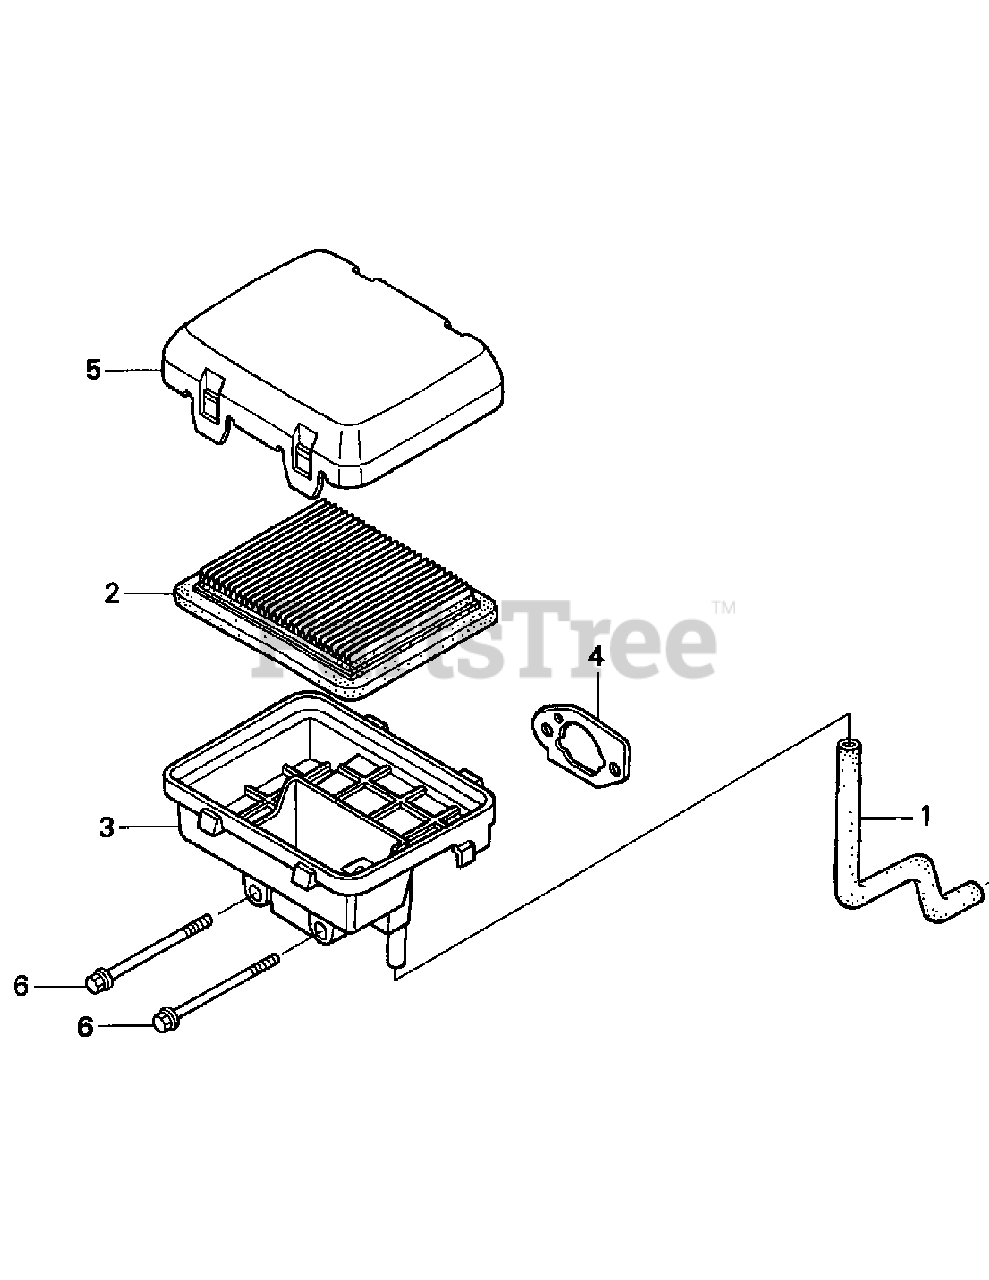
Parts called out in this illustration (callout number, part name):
1	Tube, Breather
2	Element, Air Cleaner
3	Case Comp., Air Cleaner
4	Packing, Air Cleaner
5	Cover, Air Cleaner
6	Bolt, Flange, 6X112 (Ct200)
